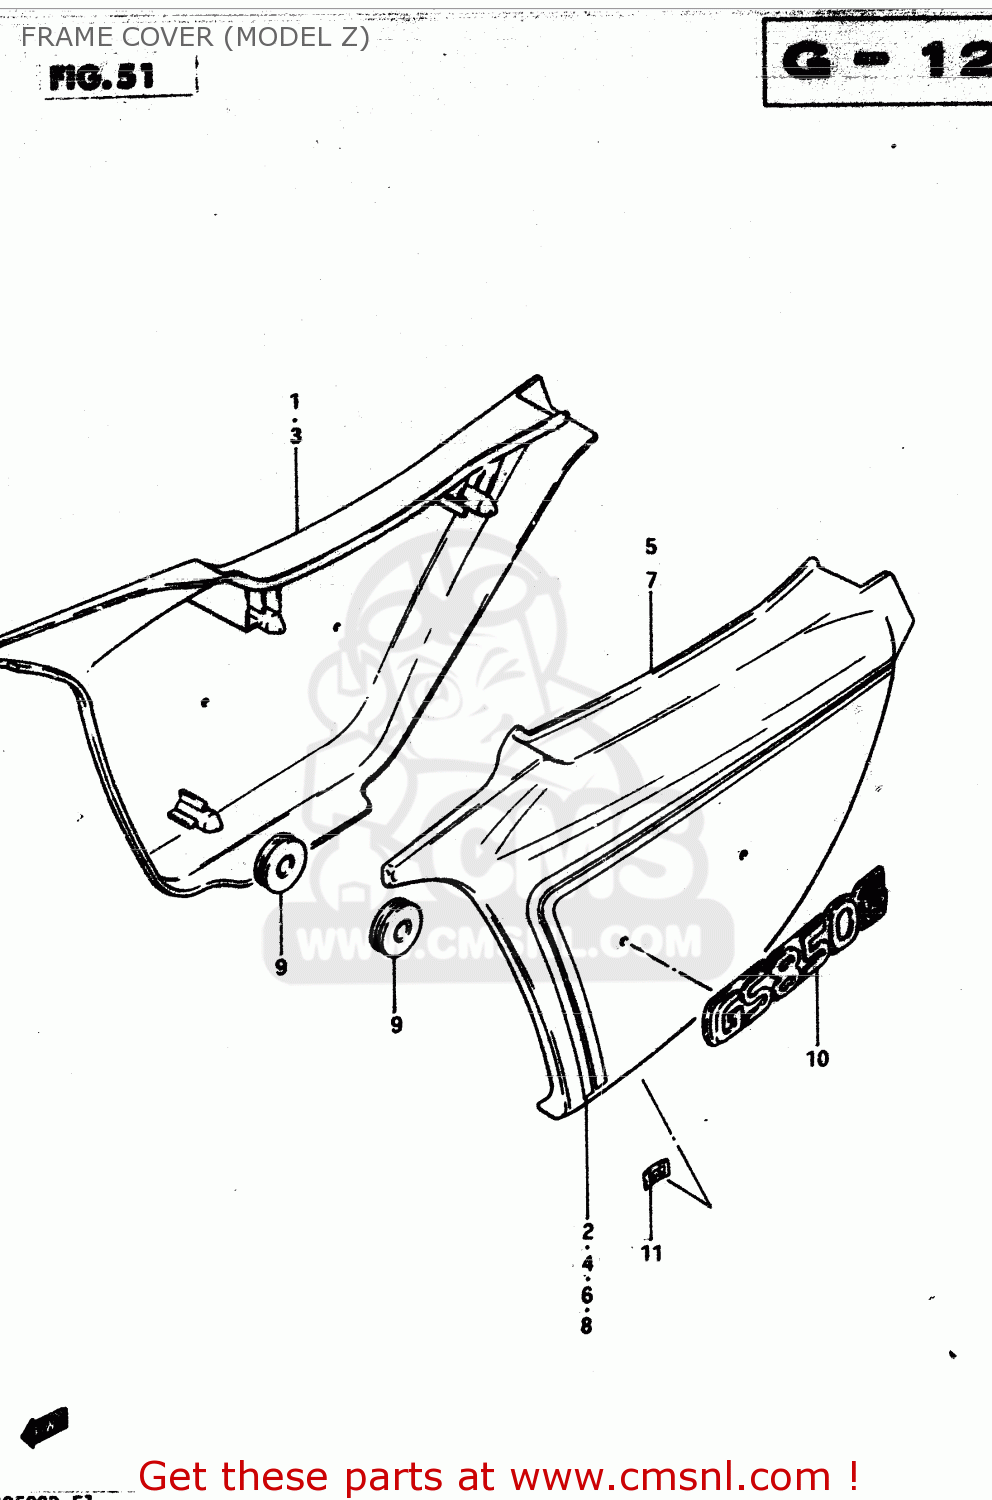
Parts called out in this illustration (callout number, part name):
1	COVER, FRAME RH (RED)
2	TAPE, RH
3	COVER, FRAME RH (BLUE)
4	TAPE, RH
5	COVER,FRAME LH
6	TAPE, LH
7	COVER, FRAME LH (BLUE)
8	TAPE, LH
9	CUSHION
10	EMBLEM
11	NUT
